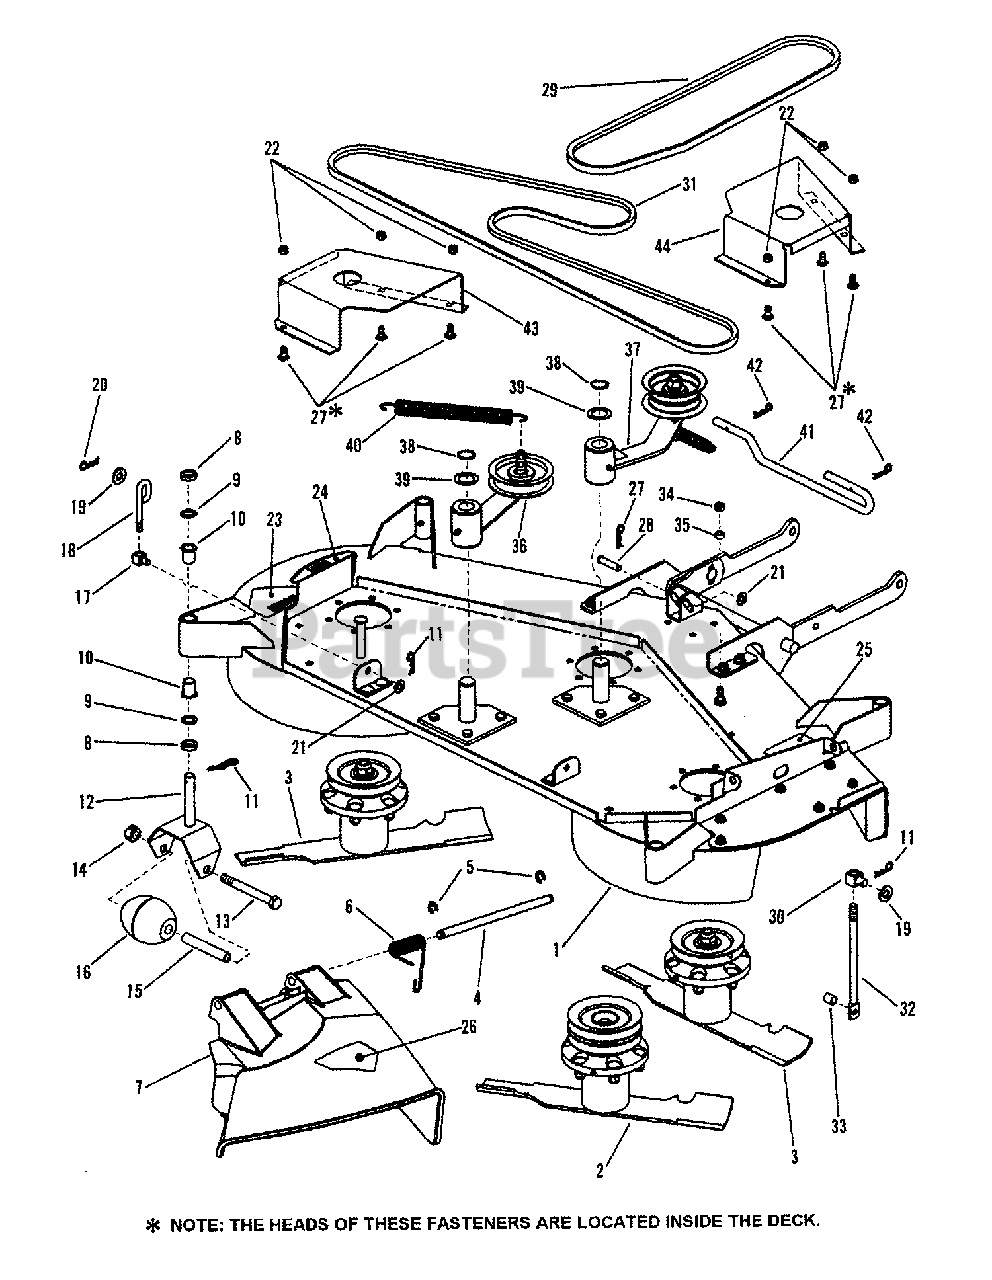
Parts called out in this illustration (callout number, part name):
1	ASSEMBLY, 48" Deck (see previous page)
2	ASSEMBLY, 48" Drive Spindle
3	ASSEMBLY, 48" L.H./R.H. Spindle
4	PIN, Chute Hinge
5	RING, Retaining
6	SPRING, Torsion (Side Chute)
7	CHUTE, Side Discharge
8	SPACER, Blade
9	WASHER, .64 x .99 x .05 Flat
10	BEARING, 1/2 x 3/4" Plastic
11	HAIR PIN, 3/32 x 1.5"
12	WELDMENT, Anti-Scalp Wheel
13	SCREW, 1/2-20 x 4-1/2" Hex Head Cap, GR5
14	NUT, 1/2-20 Hex Center Lock, GR5 or B
15	SLEEVE, Wheel Caster
16	ROLLER, Low Density Polyethylene
17	SWIVEL, Brake Link
18	ROD, Rear Lift- 48" Deck
19	WASHER, .531 x 1.062 x .121 Flat SAE
20	COTTER PIN, 1/2" Self Lock
21	WASHER, 3/8" Flat SAE
22	NUT, 5/16-18-3B Hex Nyloc
23	DECAL, Danger, Cut Finger
24	DECAL, 48" Deck
25	DECAL, Chute/Deflector
26	DECAL, CPSC Heavy Adhesive
27	BOLT, 5/16-18 x 3/4" Short Neck Carriage, GR5
28	PIN, 3/8 x 1-1/2" Clevis
29	BELT, HA Sect. 50.65" (Electric Clutch)
30	SWIVEL, Lift, 1/2-13 thread
31	BELT, HA Sect., 94.50" effective length (TTK50 Traction Drive)
32	ROD, Front Lift- 48" Deck
34	NUT, 3/8-16 Hex Center Lock, GR5 or B
35	SPACER, Tie Rod
36	ASSEMBLY, Deck Idler
37	ASSEMBLY, Drive Idler Arm
38	RING, 1" External Retaining
39	BUSHING, 1" Machine
40	SPRING, Extension- Primary Idler
41	PIN, Deck Hanger Improved
42	HAIRPIN, .148 x 2.62
43	COVER, L.H. Spindle
44	COVER, R.H. Spindle
